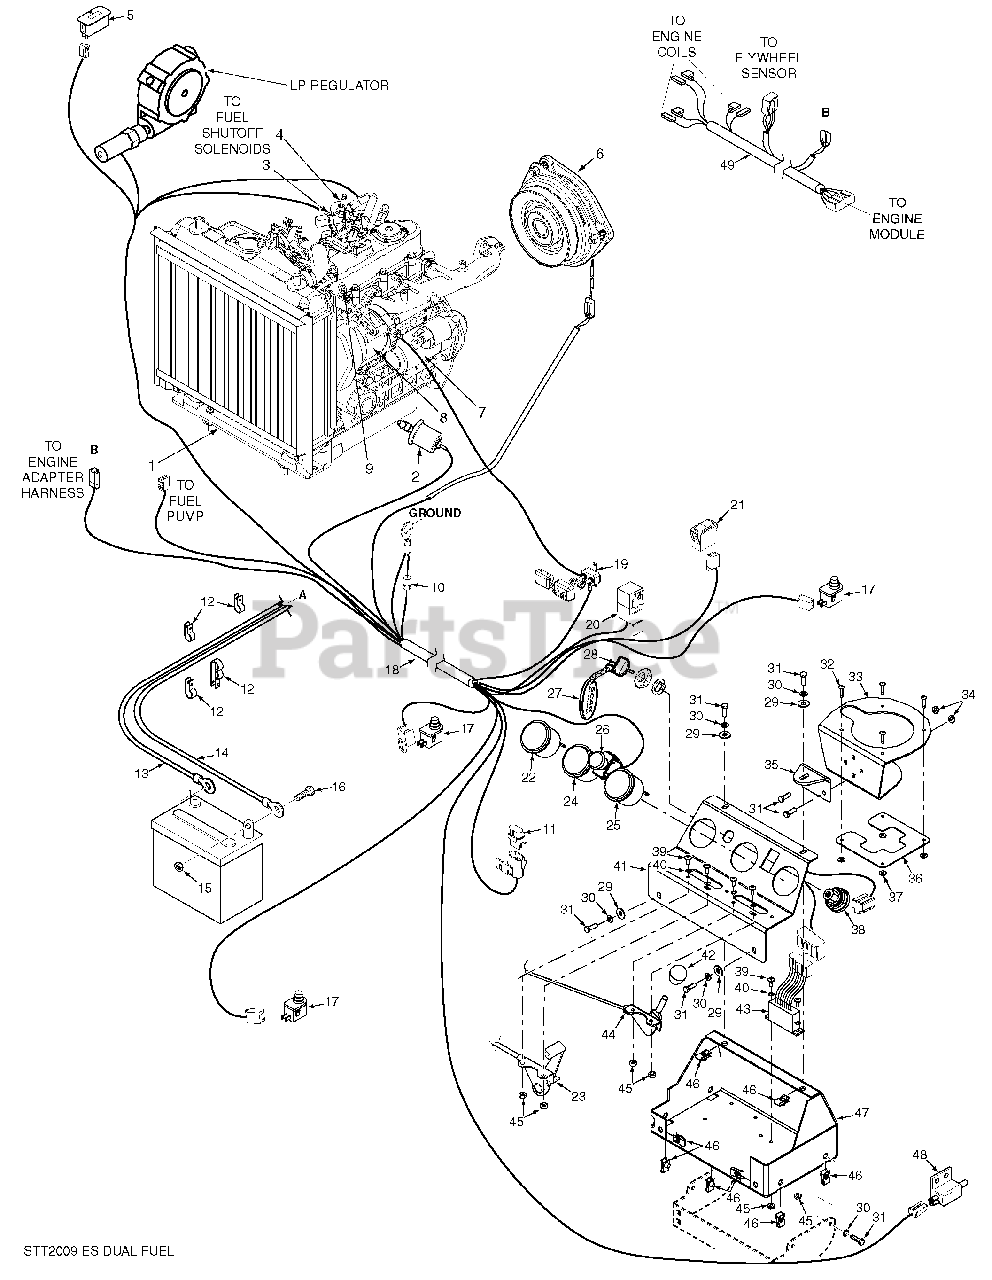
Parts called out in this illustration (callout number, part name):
1	Fuel Pump
2	Oil Pressure Sender
3	LP Shutoff Solenoid
4	Fuel Shutoff Solenoid
5	Hourmeter
6	Clutch, Ogura GT 3.5 - 1.125 Bore
7	Starting Motor
8	Alternator
9	Sending Unit, Water Temp.
10	Diode
11	Fuse, 20 AMP
12	Clamp, Cable 1/2" ID.
13	Cable, Battery - Red
14	Cable, Battery - Black
15	Nut, Hex 1/4-20
16	Bolt, Hex Head 1/4-20 x .5" Battery
17	Switch, Interlock, Normally Open
18	Main Wire Harness, STT Dual Fuel
19	Circuit Breaker, 50 AMP
20	Relay, 12V
21	Switch, Fuel Selector
22	Volt Meter
23	Indicator Light, Glow Plugs
24	Engine Oil Pressure Gauge
25	Water Temperature Gauge
26	Switch, PTO
27	Key Assembly w/Fob
28	Key, Ignition
29	Flat Washser, 1/4"
30	Lockwasher, 1/4"
31	Bolt, Hex Head 1/4-20 x 3/4"
32	Pop Rivet, 3/16" x 5/8"
33	Cupholder
34	Nut, Elastic Stop 1/4"-20
35	Bracket, Cupholder Mounting
36	Retainer, Cupholder
37	Flatwasher, 0.196 ID.
38	Key Switch
39	Screw, Phillips Washer Head #10-32 x 1/2"
40	Lockwasher, #10 External Tooth
41	Instrument Panel, Top w/Decals
42	Knob, Throttle
43	Electronic Control Module
44	Throttle Control
45	Nut, Hex #10-32
46	U-Nut, 1/4-20
47	Base, Instrument Panel
48	Switch, Interlock, Park Brake Normally Open
49	Wire Harness Adapter, Kubota Dual Fuel
